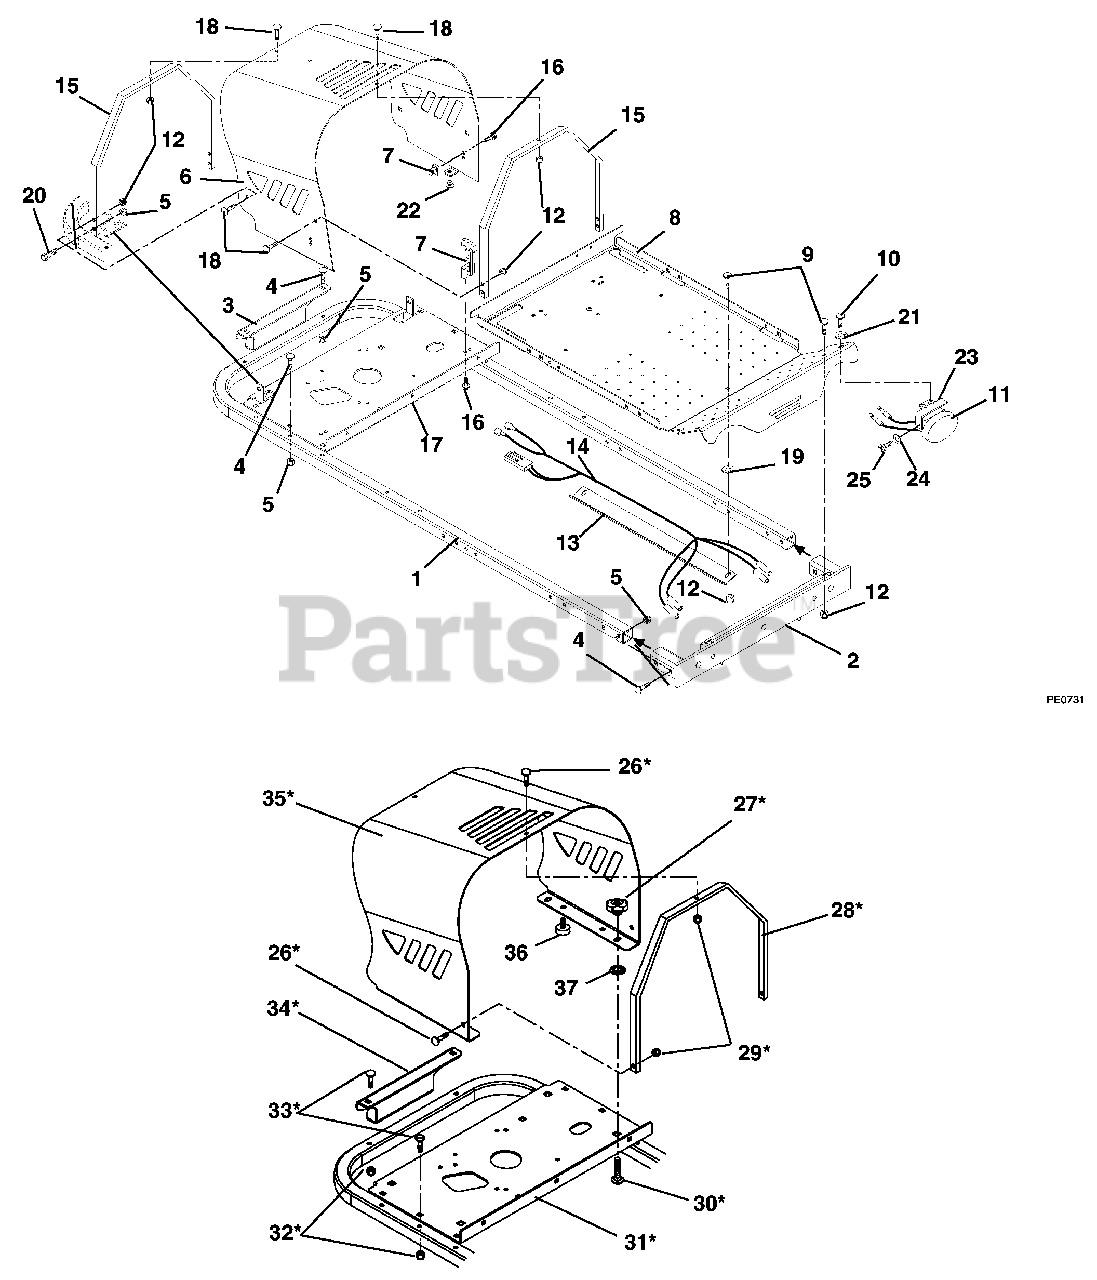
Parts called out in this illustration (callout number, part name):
1	TUBE-FRAME BLK
2	WMT, AXLE MOUNT
3	TRAILER HITCH
4	BLT-RDHDSQNK .38-16X2.25 G5BZ
5	NUT-LK-TOP-FLG .38-16 BLKZC
6	HOOD, ZOOM
7	LATCH, RUBBER
8	FOOTREST
9	BLT-RDHDSQNK .31-18X.75 G5BZ
10	SCR-CAP BTHD.31-18X.50 GR5 YZ
11	LIGHT-CONS RIDE ON- SEE B-2124
12	NUT-LK-TOP-FLG .31-18 BLKZC
13	BKT-HARNESS
14	HARNESS, LIGHT
15	BRACE, HOOD
16	@SCR-MCH 10-24X.50 HWH YWZC
17	PLATE, ENGINE
18	BLT-RDHDSQSHNK .31-18X.62 BKZC
19	WSHR-FL-STL .328X.87X.179 YWZC
20	BOLT-SHLDR .375-16X.150
21	@WSHR-LK .31X.078 REG YWZC
22	BUTTON BUMPER
23	WMT, LIGHT BRACKET
24	WSHR-LK 4MMX1MM REG CL ZINC
25	SCREW-M4X.07X8 SHCS CLZNC
26	BLT-RDHDSQSHNK .31-18X.62 BKZC
27	KNOB-CLAMPING, .312-18 NYLOC
28	BRACE, HOOD
29	NUT-LK-TOP-FLG .31-18 BLKZC
30	@BLT-RDHDSQNK .31-18X1.00 G5YZ
31	BKT-ENG MOUNT
32	NUT-LK-TOP-FLG .38-16 BLKZC
33	BLT-RDHDSQNK .38-16X2.25 G5BZ
34	TRAILER HITCH
35	HOOD-ZOOM
36	BUTTON BUMPER
37	NUT-PUSH .312
